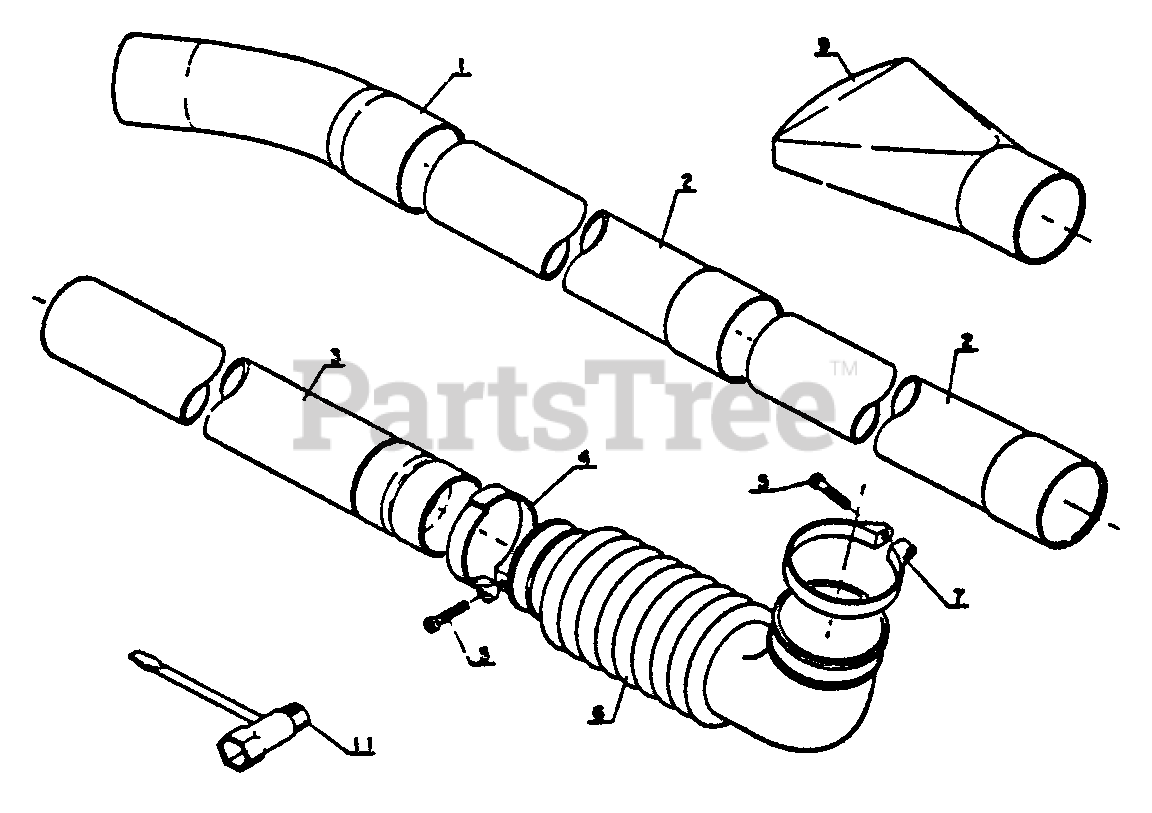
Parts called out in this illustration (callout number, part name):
1	TUBE, BLOWER - CURVED
2	TUBE, BLOWER - STRAIGHT
3	TUBE, BLOWER - SWIVEL
4	CLAMP
5	SCREW - 5X25
6	TUBE, BLOWER - FLEXIBLE
7	CLAMP
9	NOZZLE - FAN HEAD
11	T-WRENCH - 13X19mm
